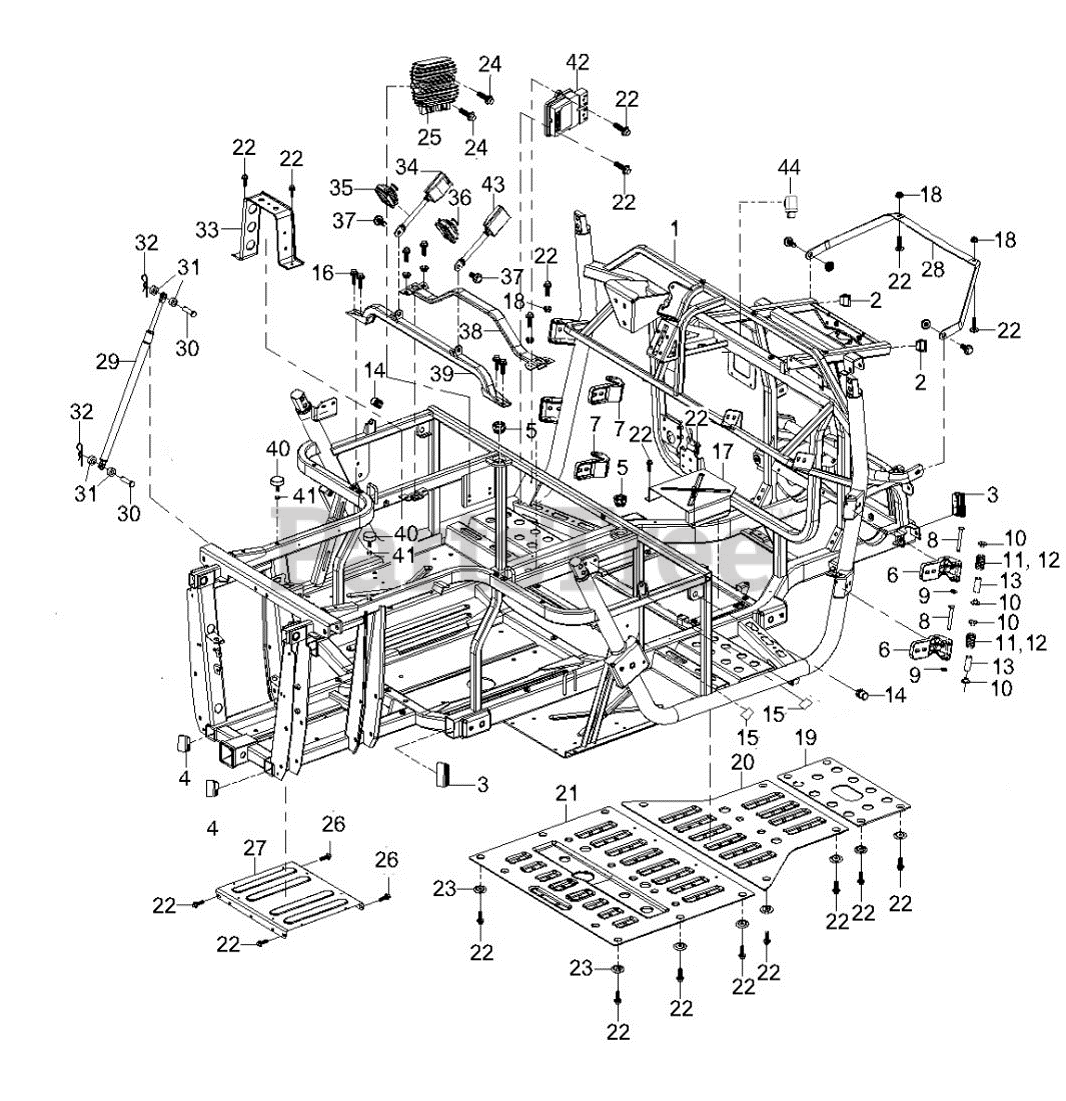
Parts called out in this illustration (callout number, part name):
1	FRAME
2	PLASTIC CAP 30X30
3	RUBBER BLOCK
4	PLASTIC CAP 40X40
5	RUBBER WASHER
6	DOOR HINGE
7	DOOR HINGE
8	SHOULDER PIN 8X70.5
10	PLASTIC BUSHING
11	TORSION SPRING
12	TORSION SPRING
14	DOOR DAMPER I
15	BATTERY CUSHION
16	HEXAGON FLANGE BOLT M8X20
17	PEDAL PLATE
18	HEX FLANG NUT M6
19	FRONT SKID PLATE
20	MIDDLE SKID PLATE
21	REAR SKID PLATE
22	HEXAGON FLANGE BOLT M6X16
23	CAP WASHER
24	HEXAGON FLANGE BOLT M6X35
26	HEXAGON FLANGE BOLT M6X25
27	DIFF HEAT SHIELD (REAR)
28	HOOD STRAP
29	GAS SPRING ASSEMBLY - CARGO BED
30	SHOULDER PIN 12X47
31	RUBBER WASHER 13 x 10
32	SPRING PIN
33	BATTERY BOX STRAP
34	SEAT BELT BUCKLE
35	SEAT BELT BUCKLE CAP LH
36	SEAT BELT BUCKLE CAP RH
37	HEX FLANGE BOLT M10X1.25X20
38	SEAT STIFFENER SHELF KIT
39	SEAT BELT MOUNTING BRACKET
40	SPIRAL CUSHION GASKET
41	NUT HEXAGON FLANGE HEAD M8
42	ECU CONTROLLER (550) (MY18+)
42	ECU 550 (CARB)
42	ECU CONTROLLER (750) (MY18+)
42	ECU 750 (CARB)
43	PASSENGER SIDE SEAT BELT
44	OIL PRESSURE SIGNAL CONTROLLER
